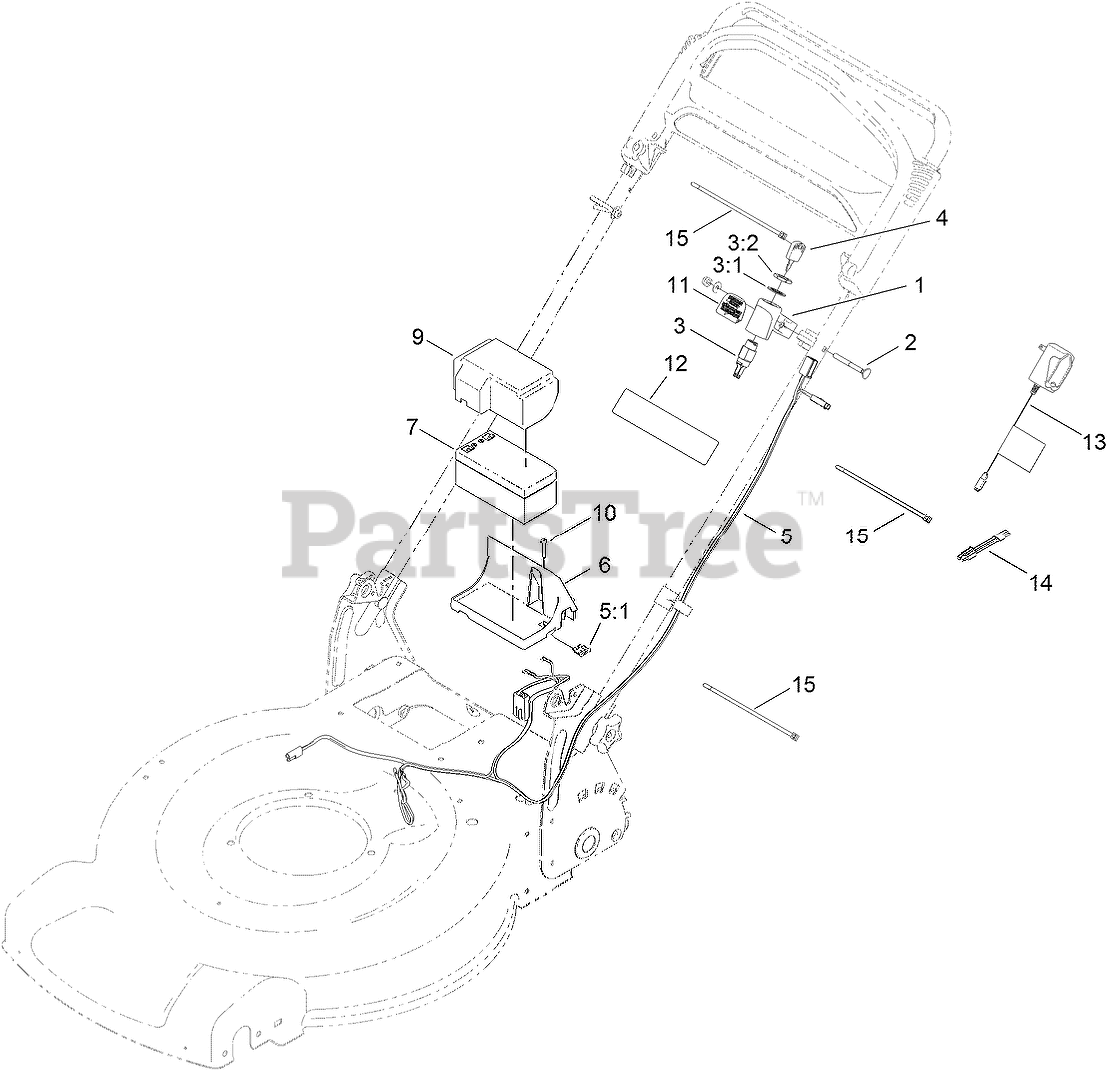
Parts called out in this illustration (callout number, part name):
1	MOUNT-SWITCH
2	SCREW-HANDLE
3	STARTER SWITCH ASM
3:1	WASHER-TOOTH, INTERNAL
3:2	NUT-HH
5	HARNESS-WIRE
5:1	FUSE-40 AMP
6	TRAY-BATTERY
7	BATTERY-WET
9	COVER-BATTERY
10	SCREW-PPH, PLASTITE
11	DECAL-ELECTRIC START
12	DECAL-WARNING
13	CHARGER-EUROPEAN, 12V DC
14	ADAPTER-CHARGER
15	TIE-CABLE
